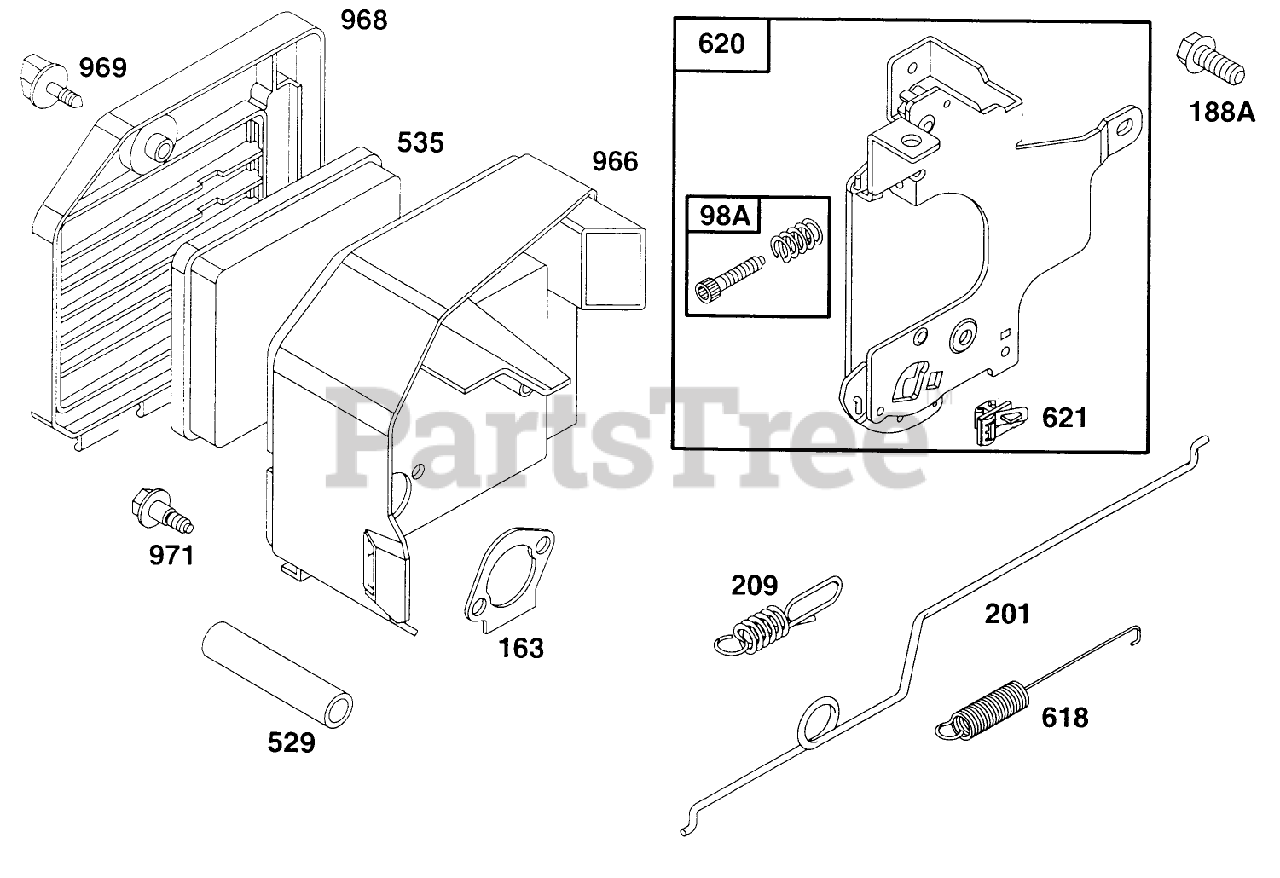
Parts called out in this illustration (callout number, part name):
98A	SPEED ADJUST. SCREW ASM
163	AIR CLEANER GASKET
201	GOVERNOR LINK
209	GOVERNOR SPRING
529	BREATHER TUBE
535	FILTER ELEMENT
618	RETURN SPRING
621	STOP SWITCH
966	AIR CLEANER BASE
969	AIR CLEANER SCREW
971	AIR CLEANER SCREW
